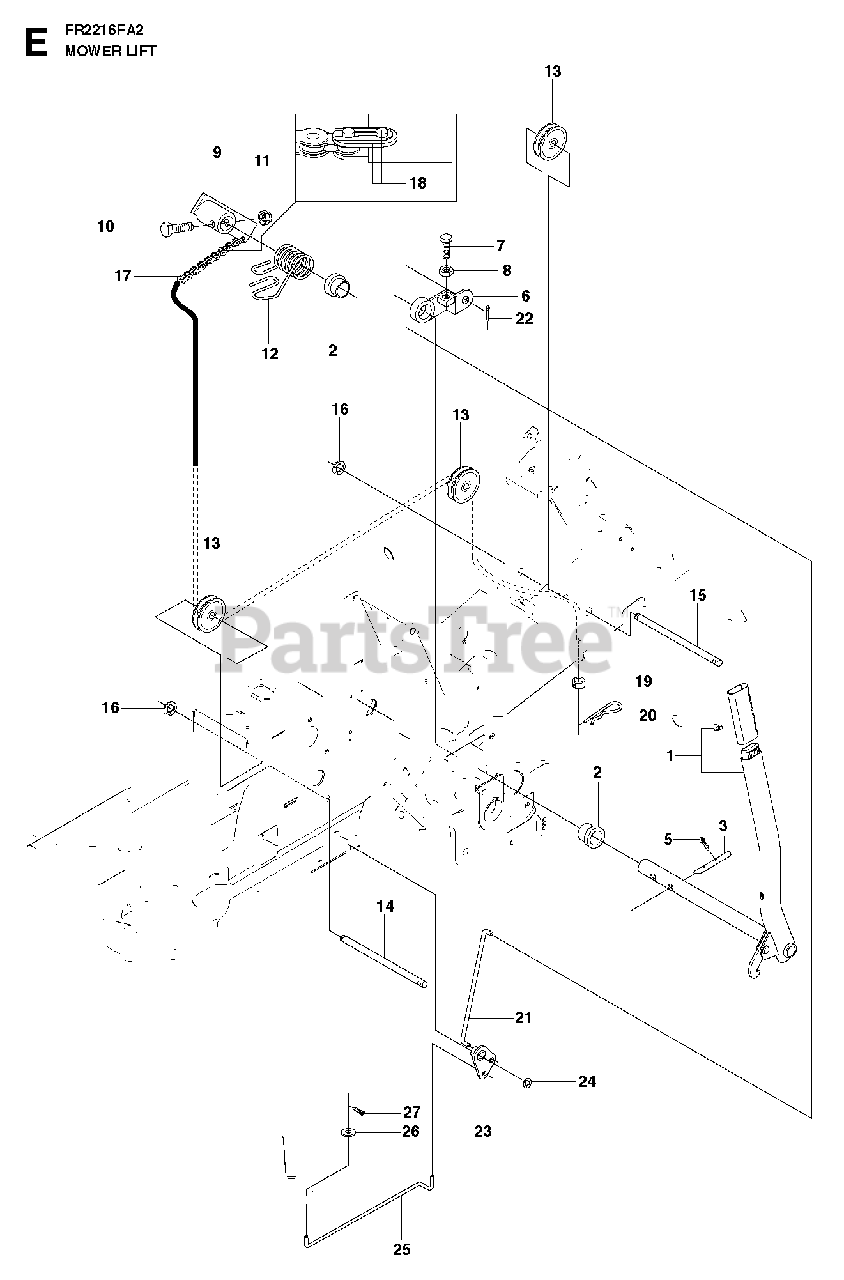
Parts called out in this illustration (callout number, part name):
1	LIFTING LEVER ASSY
2	BUSH
5	SPLIT PIN
6	LEVER CLUTCH
9	LIFTING ARM
16	LOCK RING
21	CONNECTION ROD
22	SPLIT PIN
24	RETAINING RING
25	CONNECTION ROD
27	SPLIT PIN
